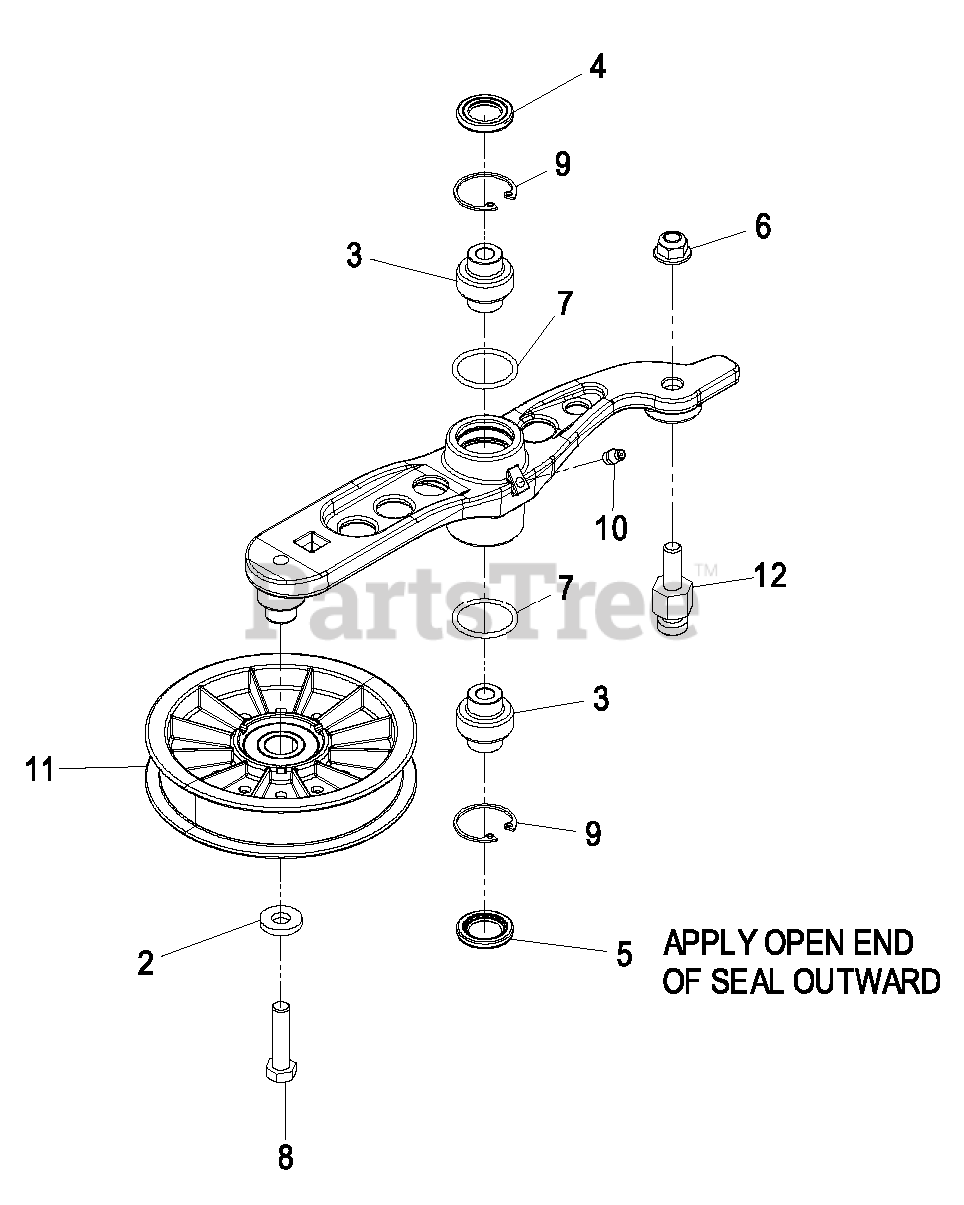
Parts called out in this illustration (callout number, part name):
3	BEARING-SPHERICAL
4	SEAL-LIP, DOUBLE
5	SEAL-LIP, SINGLE
6	NUT-HF, NI
8	SCREW-HH
9	RING-SNAP
10	FITTING-GREASE
11	PULLEY-IDLER
